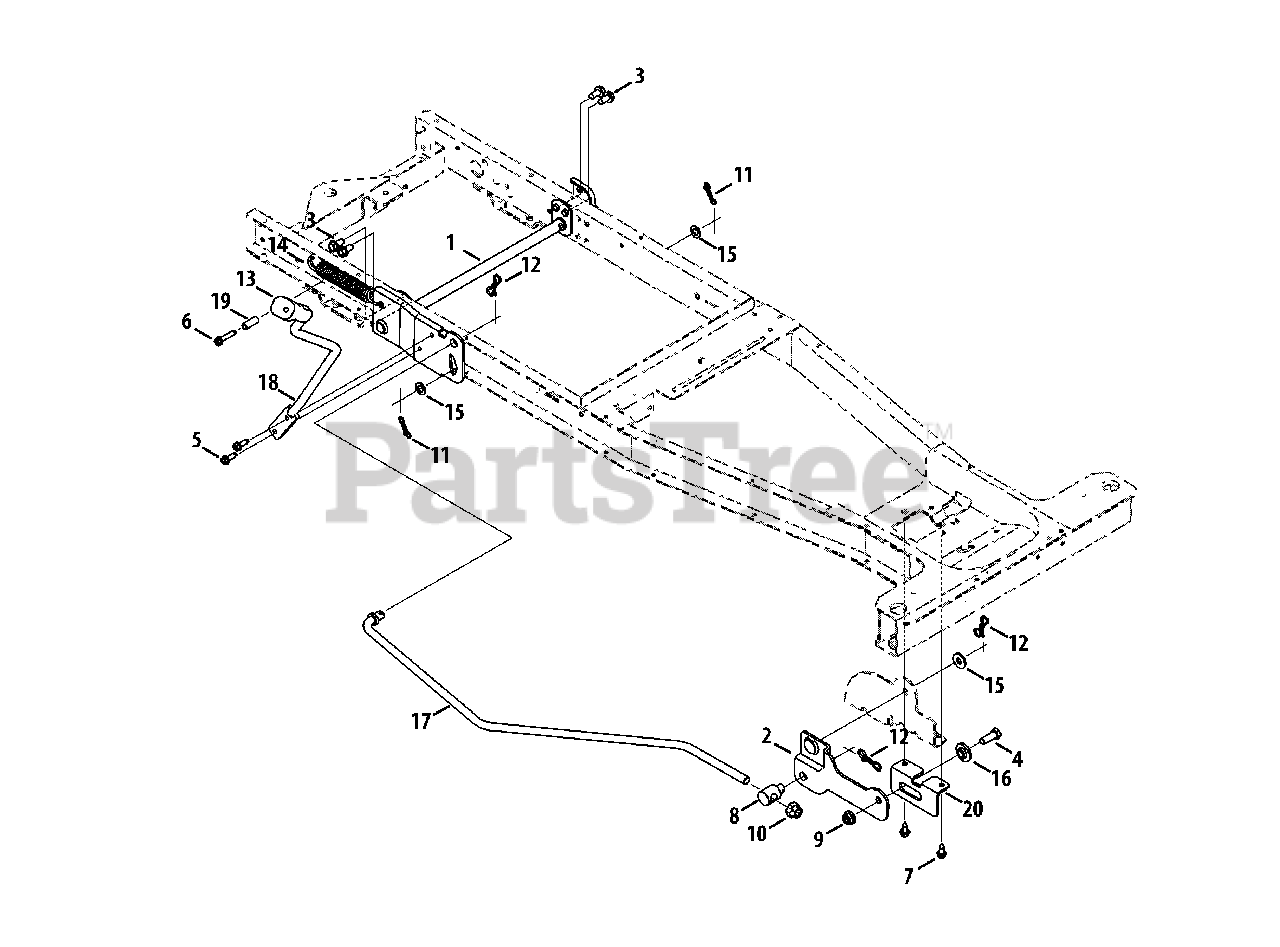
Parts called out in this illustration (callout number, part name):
1	Lift Assembly Shaft
2	Front Hanger Bracket Assembly
3	Tap Screw, 5/16-18, .750
4	Hex Head Screw, 3/8-16, 1.00
5	Tap Screw, 1/4-20, 0.750
6	Tap Screw, 1/4-20, 1.250
7	Tap Screw, 1/4-20 X .625
8	Ferrule, .50 X .50
9	Flange Lock Nut, 3/8-16
10	Flex Lock Nut, 1/2-13
11	Bow-Tie Cotter Pin, 72
12	Bow-Tie Cotter Pin, 91
13	Grip Handle, 1/2
14	Extension Spring, .85 OD X 5.915 LG
15	Flat Washer, .406 X .875 X .059
16	Shoulder Spacer, .625 ID X .169
17	Lift Link Rod
18	Deck Lift Rod
19	Spacer, .260 x .375 x 1.030 LG
20	Front Deck Mounting Bracket
